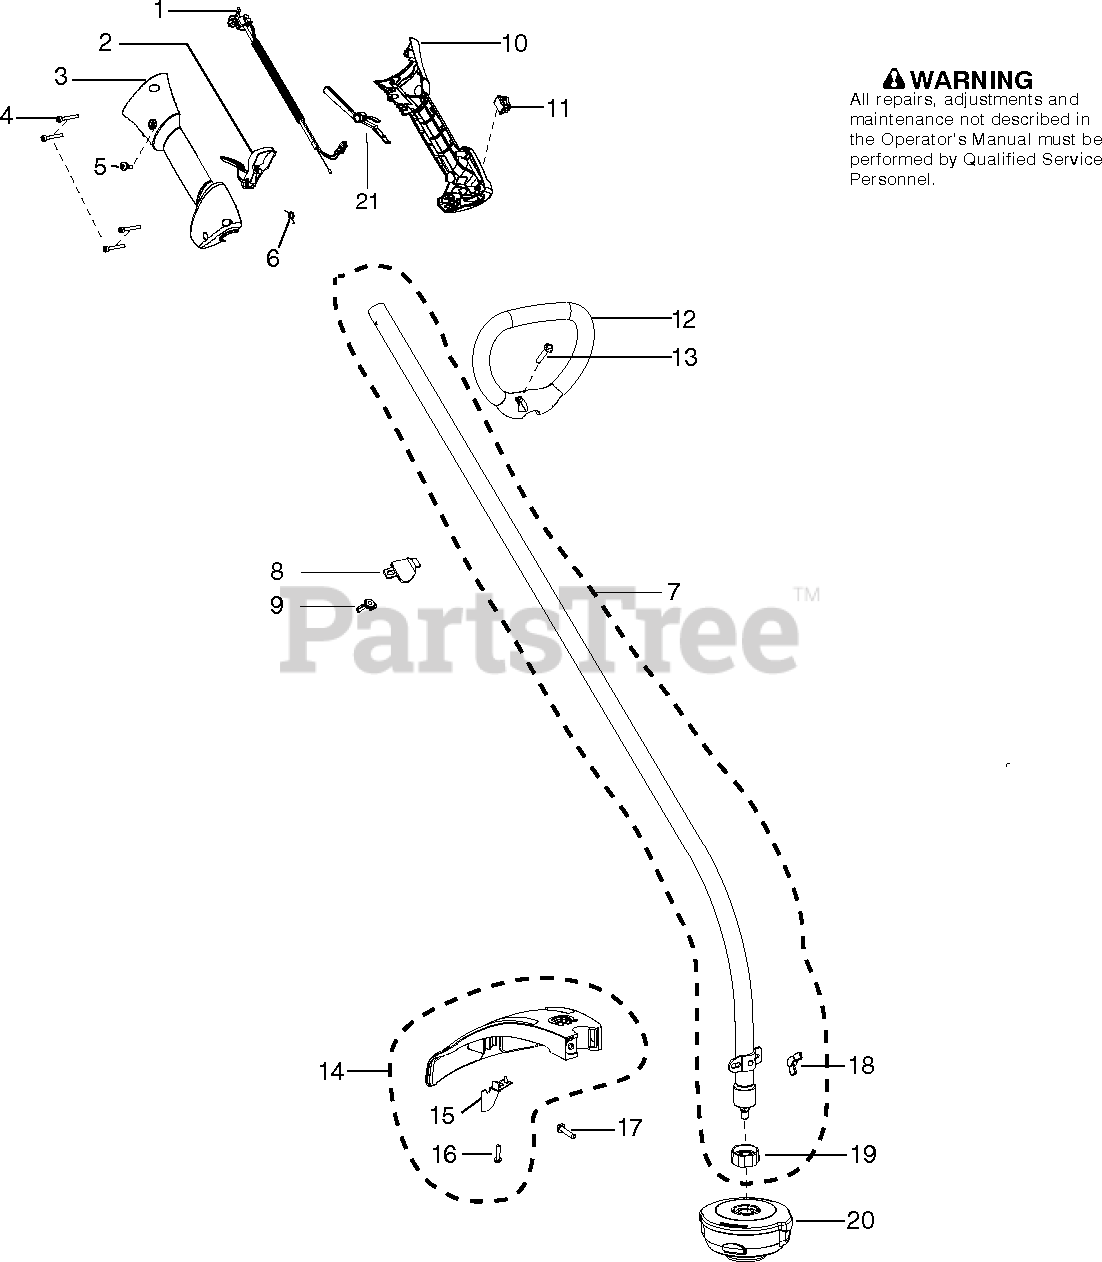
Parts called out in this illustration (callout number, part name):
1	ASSY THROTTLE
3	HOUSING RIGHT
6	SPRING TRIGGER
7	KIT SERVICE DRIVESHAFT
8	CLAMP ASSIST HANDLE
9	WINGNUT, TYPE 2
10	HOUSING THROTTLE LH
12	HANDLE ASSIST
13	BOLT, TYPE 2
16	SCREW 10-14X3/4 PLASTITE
17	BOLT, TYPE 2
18	WINGNUT, TYPE 2
20	T25 3/8" RH TRIMMER HEAD
21	THROTTLE LOCKOUT
